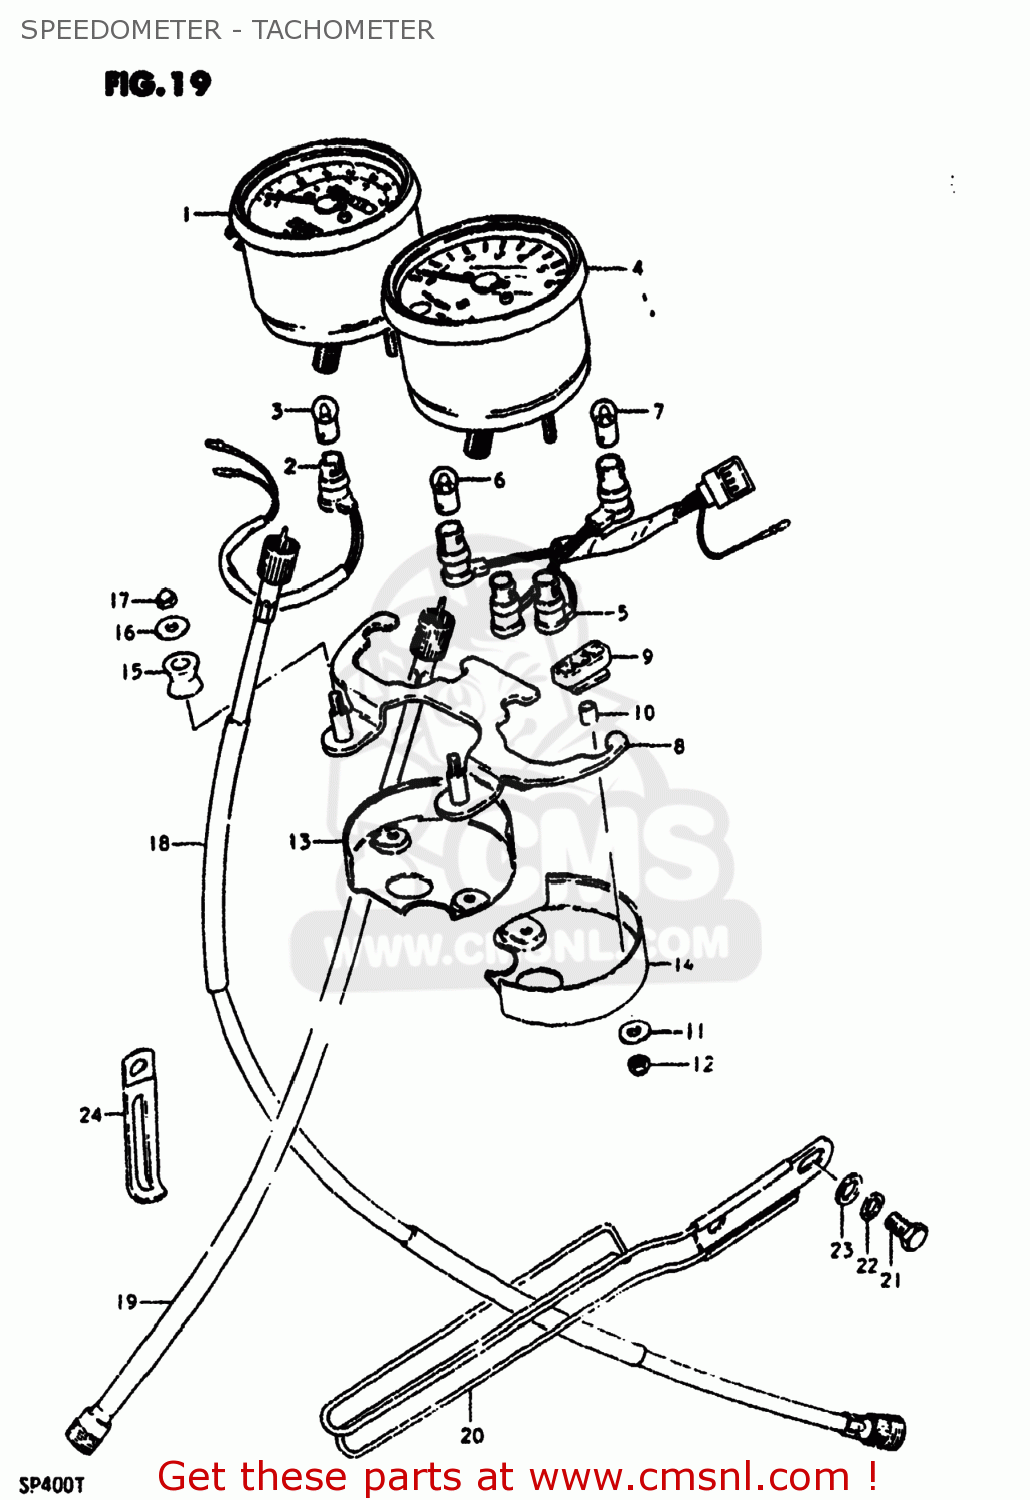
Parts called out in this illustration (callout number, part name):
1	SPEEDOMETER ASSEMBLY
2	SOCKET,METER
3	BULB(6V/3W)
4	METER,TACHOMETER
5	SOCKET,TACHOMETER
6	BULB(6V1.7W,STANLEY,A61A)
7	BULB(6V/3W)
8	BRACKET,COMBINATION METER
9	CUSHION
10	SPACER
11	WASHER (5.5X16X1.2)
12	NUT
13	COVER,METER,UNDER
14	PLATE,TACHOMETER UNDER
15	CUSHION
16	WASHER
17	NUT
18	CABLE ASSY,SPEEDOMETER
19	CABLE ASSEMBLY,TACHOMETER
20	GUIDE,CABLE
21	BOLT 8X12
22	LOCK WASHER
23	WASHER
24	CLAMP L:35
